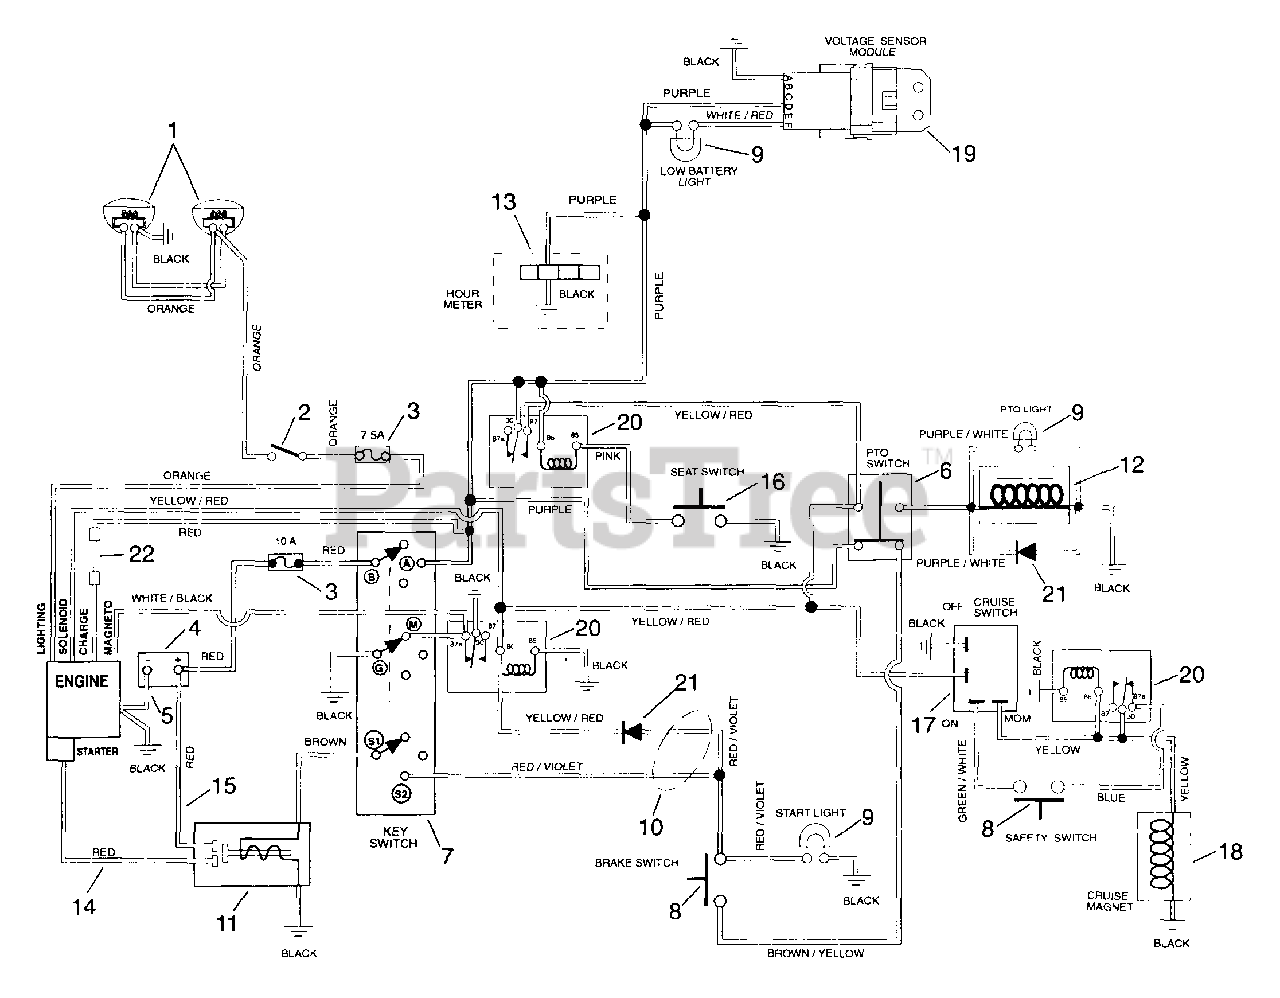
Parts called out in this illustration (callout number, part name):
1	Headlights-Right Hand
1	Headlights-Left Hand
2	Switch-Light
4	Battery W/Tube
5	Ground Cable
6	PTO Knob/Switch Assembly
7	Key Switch
8	Switch-Single Pole N.O.
10	Wire Harness-1440H B & S
11	Solenoid
12	Electric Clutch/Brake
13	Hourmeter Kit-Sierra
14	Starter Cable 22"
15	Starter Cable 6.75"
16	Switch-Seat
17	Switch-Cruise
19	Module-Voltage Sensor
20	Relay
21	Molded Diode Plug-Clear Lamp
22	Wire Harness Adaptor
